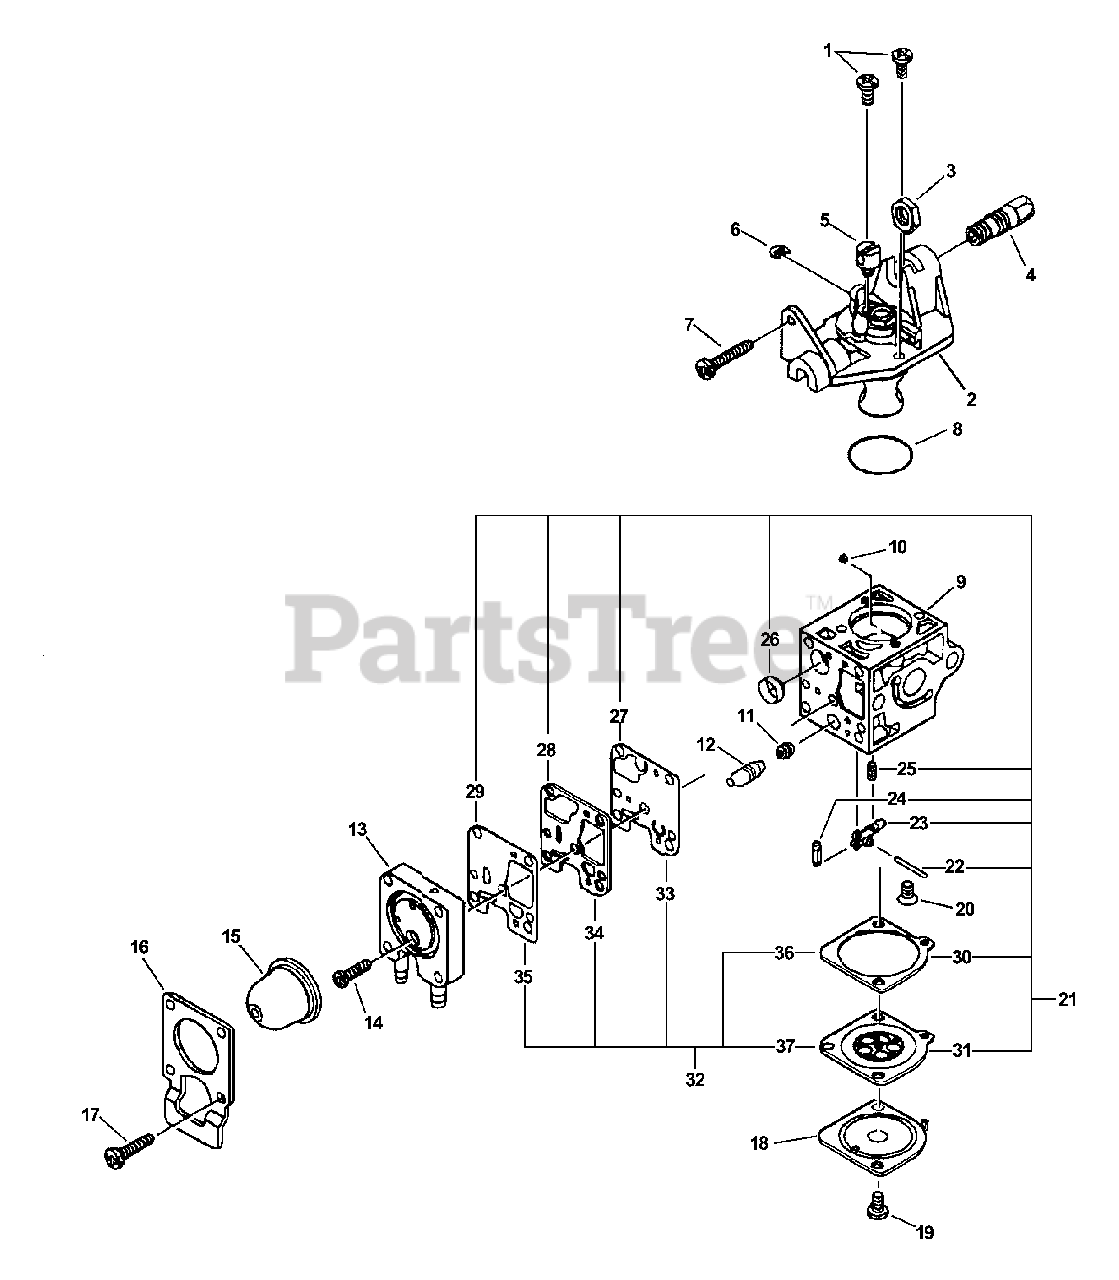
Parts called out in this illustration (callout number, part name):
2	ROTOR COVER ASSY
4	ADJUSTER, THROTTLE CABLE
7	SCREW, IDLE ADJUST
9	BODY, CARBURETOR
10	GUIDE, ROLLER
11	JET, MAIN
12	PLUG KIT
13	BASE, PURGE
15	BULB, PURGE
16	RETAINER, PURGE BULB
17	SCREW, PURGE BULB RETAINER
18	COVER, METERING DIAPHRAGM
20	SCREW, METERING LEVER PIN
21	REBUILD KIT
22	PIN, METERING LEVER
23	LEVER, METERING
24	VALVE, INLET NEEDLE
25	SPRING, METERING LEVER
26	STRAINER
27	DIAPHRAGM, PUMP
28	GASKET, PUMP
29	DIAPHRAGM, SURGE
30	GASKET, DIAPHRAGM
31	DIAPHRAGM, METERING
32	GASKET / DIAPHRAGM KIT
33	DIAPHRAGM, PUMP
34	GASKET, PUMP
35	DIAPHRAGM, SURGE
36	GASKET, DIAPHRAGM
37	DIAPHRAGM, METERING
